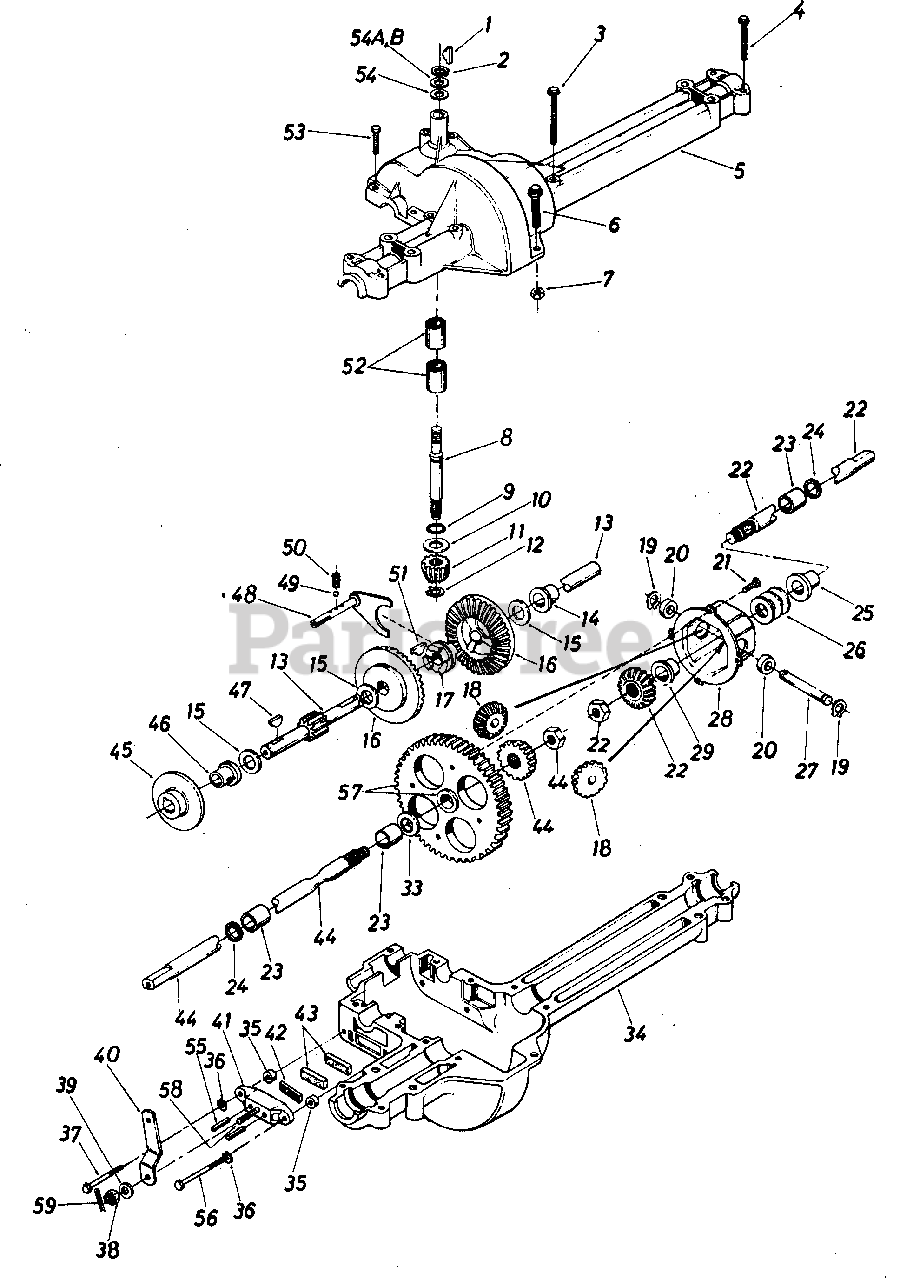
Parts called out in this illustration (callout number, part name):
1	#4 Hi-Pro Key 3/32 x 5/8" Dia.
2	Snap Ring .625" Shaft
3	Hex Bolt 1/4-20 x 1.75" Lg.
4	Hex Bolt 5/16-18 x 2.5"
5	Upper Housing
6	Hex Fl-Bolt 1/4-20 x .88" Lg.
7	Hex Nut 1/4-20 Thd.*
8	Input Shaft
9	Square Seal 5/8" I.D.
10	Thrust Washer 5/8" I.D. x 1.25" O.D.
11	Pinion Input 14T
12	Retaining Ring 7/16" Ext.
14	Flange Brg. 5/8" I.D. x 3/4"- 0 Lg.*
15	Fl-Wash.
16	Bevel Gear 42T
17	Clutch Collar
18	Miter Gear 15T (H.D.)
19	Snap Ring
20	Thrust Bearing 1/2" I.D. x 1.0" O.D.
21	Pan Head Scr. 1/4-20 x .50" Lg. w/Patch
22	Axle R.H. Ass'y.-Kit
23	Sleeve Bearing 3/4" I.D. x 1.0" Lg.
24	Oil Seal 3/4" I.D.
25	Flange Bearing 3/4" I.D. x 15/16" Lg.
26	Fl-Wash. .760" I.D. x 1.49" O.D.
27	Cross Shaft
28	Differential Housing Ass'y.
33	Fl-Wash. .760" I.D. x 1.49" O.D.
34	Lower Housing
35	Spacer .53" O.D. x 3/8" Lg.
36	L-Wash. 1/4" I.D.'
37	Hex Bolt 1/4-20 x 1.50" Lg. (Grade 5)
38	Castle Nut 5/16-24 Thd.
39	Fl-Wash. .344" I.D. x .875" O. D.
40	Actuating Arm
42	Puck Plate
43	Brake Puck
44	Axle L.H. Ass'y.-Kit
46	Flange Bearing 5/8" I.D. x 15/16" Lg.
47	Woodruff Key 3/16 x 5/8 HT
48	Shift Fork Ass'y.
49	Ball Detent .250" Dia.
50	Spring Detent
51	#9 Hi-Pro Key 3/16" x 3/4" Dia. HT
52	Needle Brg. 5/8" I.D. x 1/2"-Lg.
53	Hex Bolt 1/4-20 x 1.00 Lg.
54	Fl-Wash. 5/8" I.D. x .030
54A	Fl-Wash. 5/8" I.D. x .040
55	Actuating Pin 5/16" Dia.
56	Hex Bolt 1/4-20 x 2.50" Lg. (Grade 5)
57	Differential Gear 72T Ass'y. w/Bearing
58	Sq. Hd. Bolt 5/16-24 Thd.
59	Cotter Pin 3/32" Dia. x .50" Lg.
